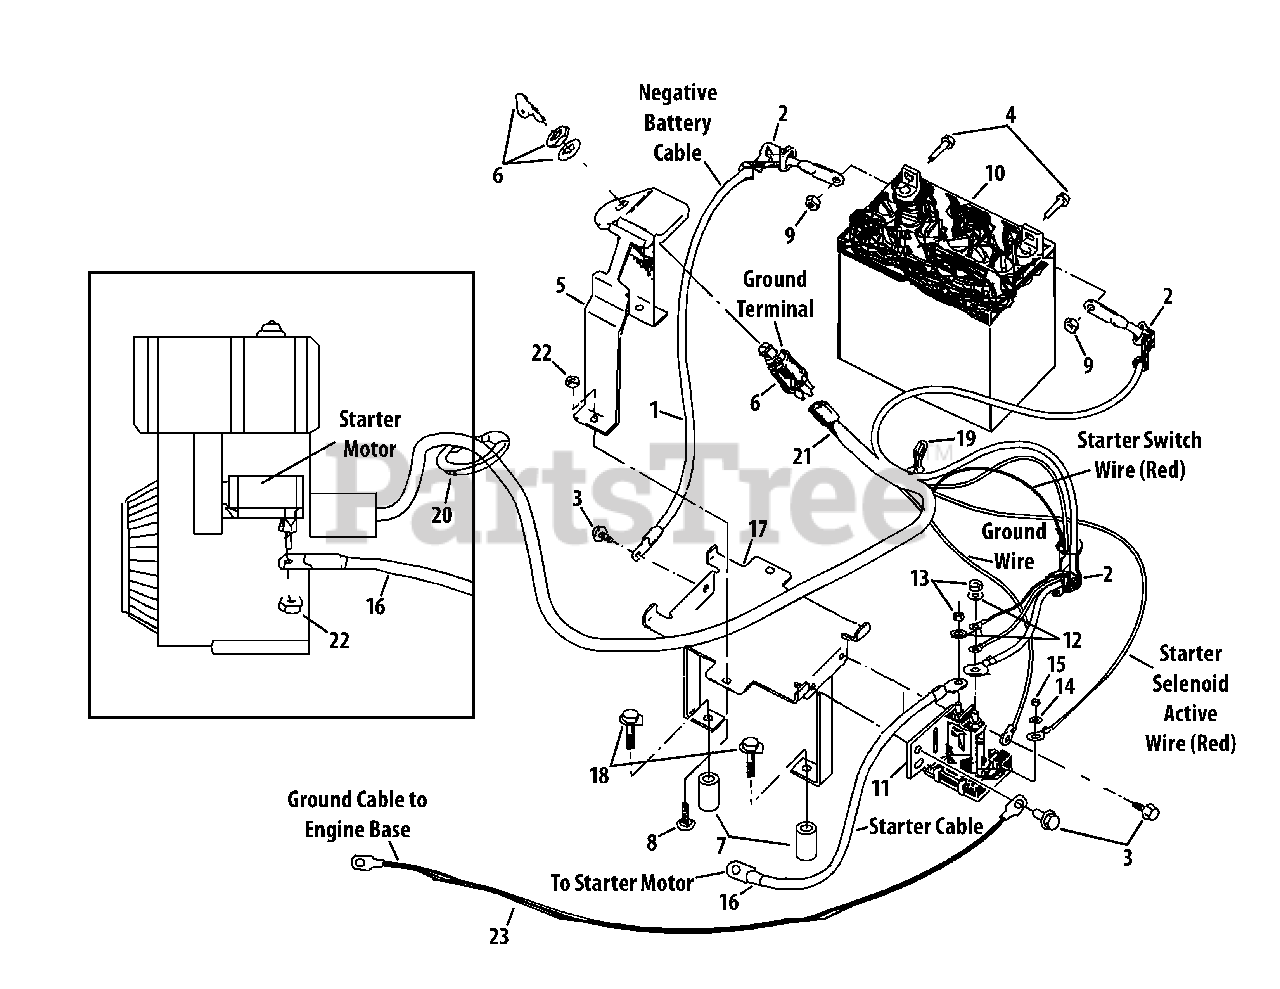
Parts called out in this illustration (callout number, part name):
1	Battery Cable
2	Terminal Insulating Boot
3	TT-Screw, 1/4"-2 x 1/2"
4	Hex Bolt, 1/4"-20 x 5/8"
5	Battery Hold-down Clamp
6	Key Switch (Incl. 2 Keys)
8	Carriage Bolt, 1/4"-20 x 1-1/4"
9	Hex Nut, 1/4"-20
10	12-Volt Battery
11	Starter Solenoid
12	Lockwasher, 5/16"
13	Hex Nut, 5/16"-24
14	External Tooth Lockwasher
15	Hex Nut, #10-32
16	Battery Cable
17	Battery Bracket
18	Hex Head Screw, 3/8"-16 x 2.75"
19	Plastic Tie
20	Plastic Tie
21	Wire Harness & Connecting Terminal Assembly
22	Flangelock Nut, 1/4"-20
23	Ground Cable
